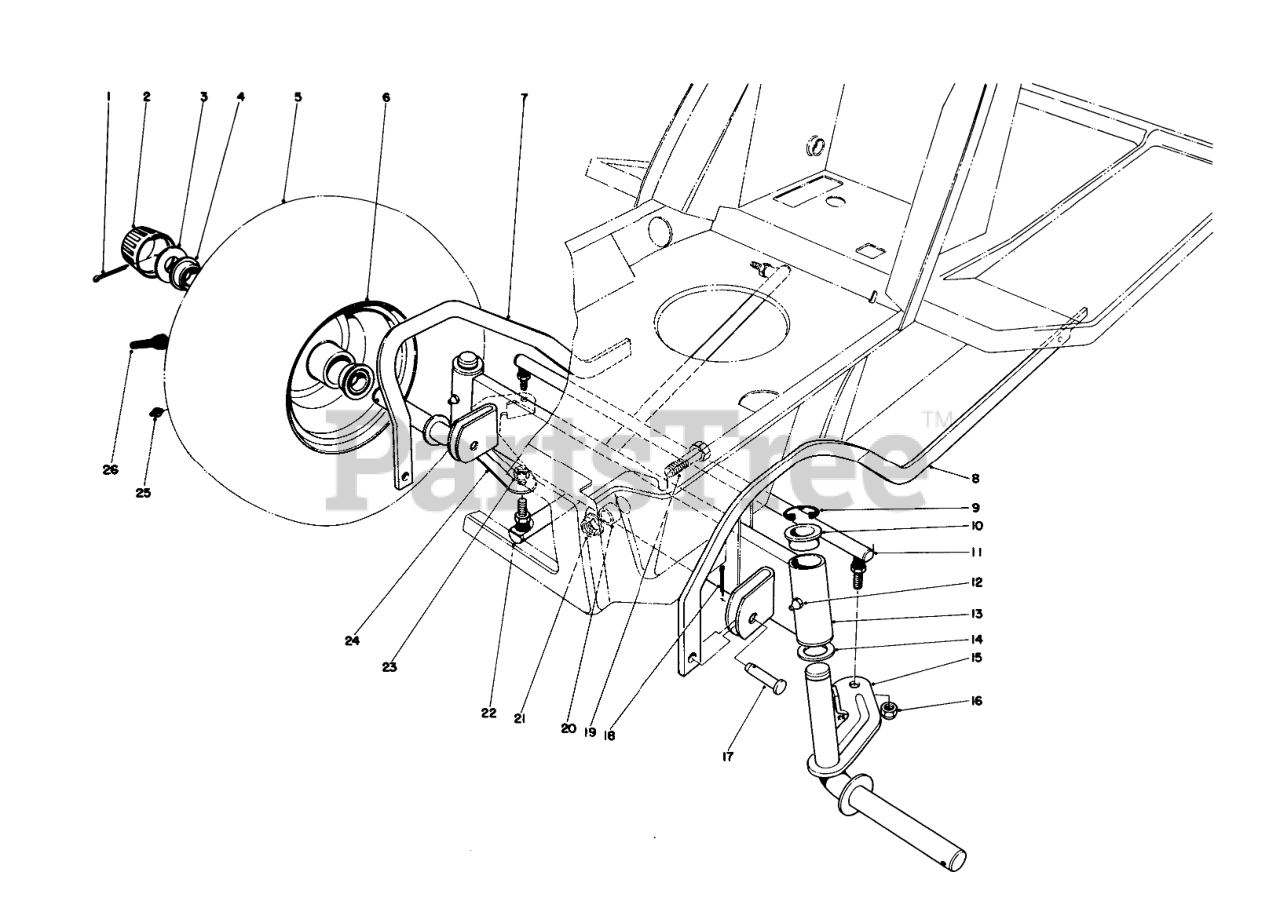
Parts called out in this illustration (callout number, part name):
1	PIN-COTTER
2	Cap-Hub
3	WASHER-PLAIN
4	Ball Bearing
5	TIRE-FRONT
6	FRONT WHEEL
7	RH DECK PARALLEL LINK R
8	LH DECK PARALEL LNKR
9	E-RING
10	BEARING-FLANGE
11	Tie Rod Steering
12	Fitting-Grease
13	Front Axle (Incl. Ref. #10)
14	WASHER-THRUST
15	Spindle L.H.
16	NUT-LOCK NI
17	PIN-CLEVIS
18	PIN-COTTER
19	SCREW-HH
20	SPACER-AXLE, FRONT
21	NUT-HF
22	Steering Arm
23	Nut
24	Spindle R.H.
25	FITTING-GREASE
26	STEM-VALVE
